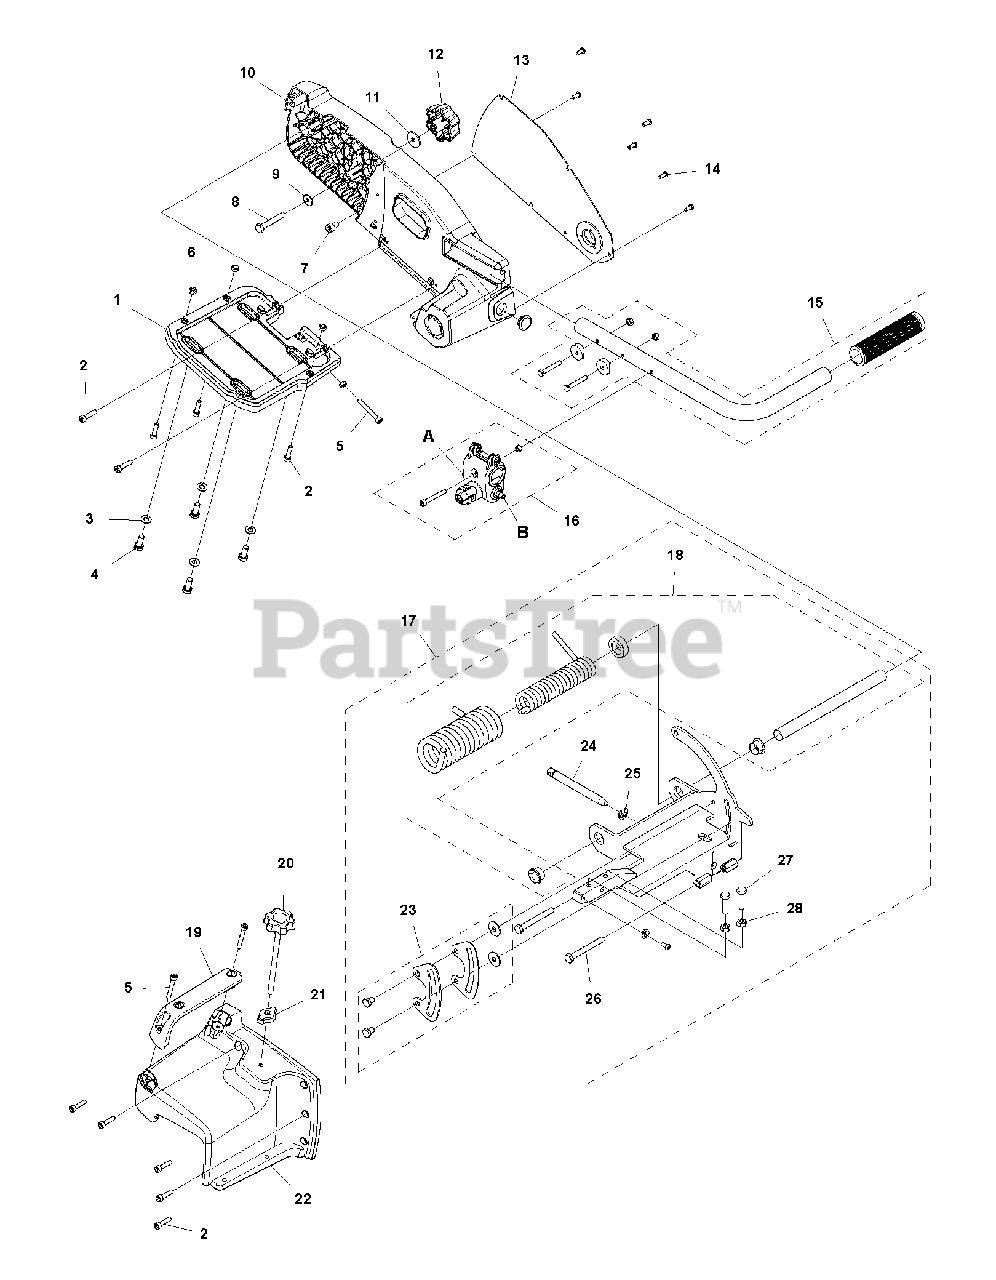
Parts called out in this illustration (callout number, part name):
2	SCREW IHSCM
3	WASHER
6	HEXAGON LOCKING NUT2 are included in kit 15
28	HEXAGON NUT
